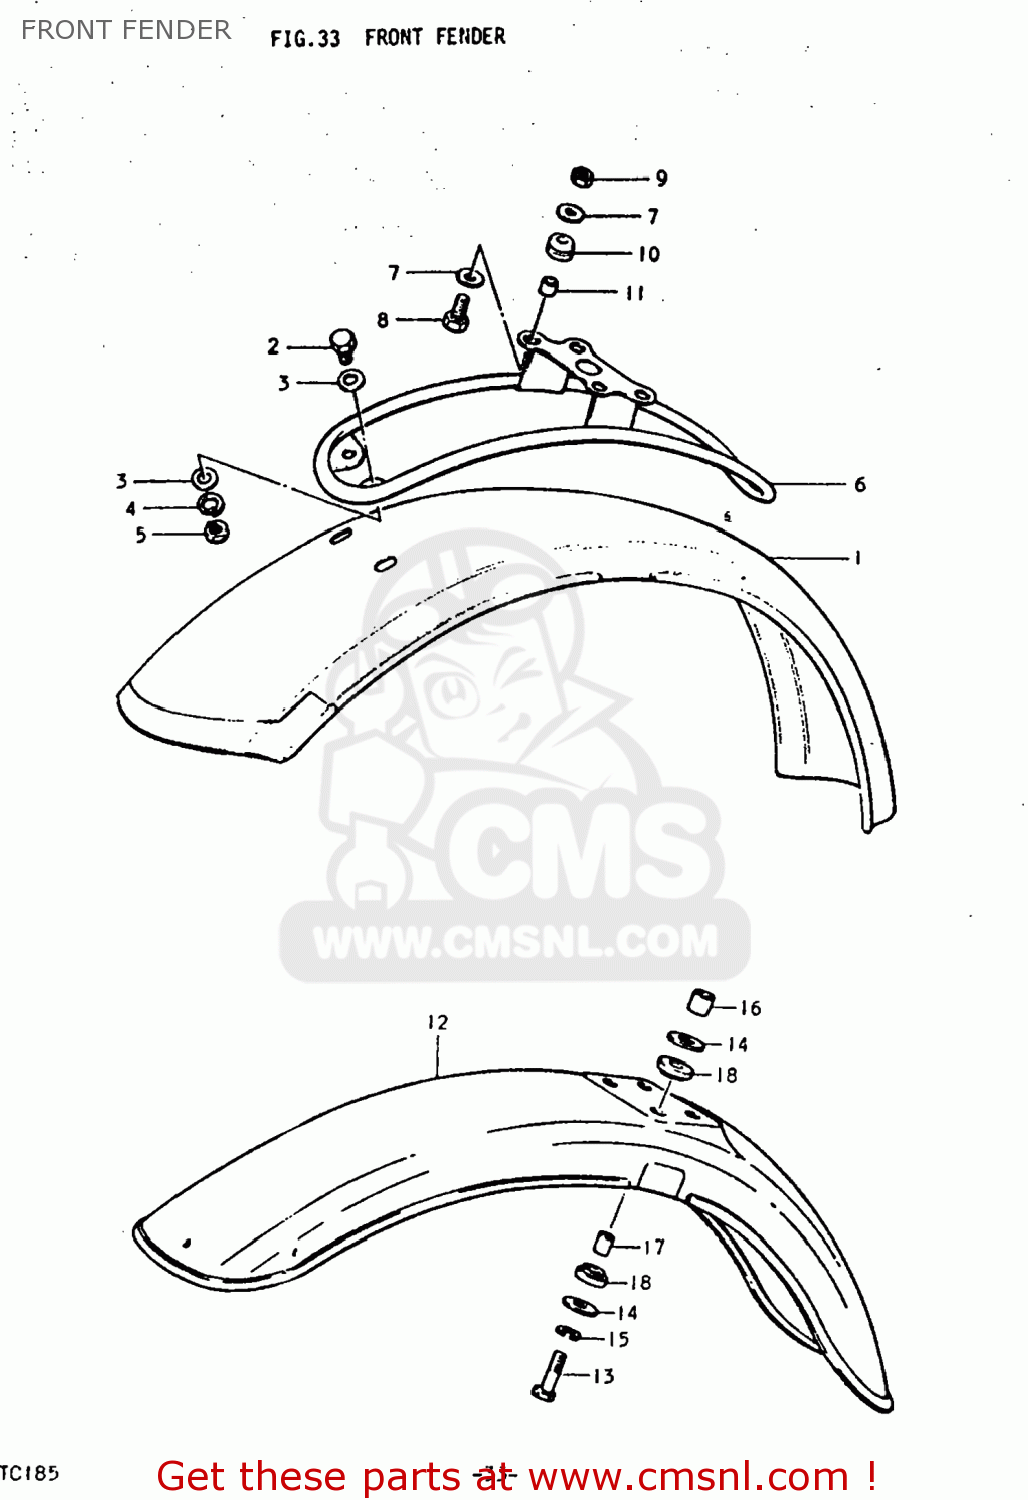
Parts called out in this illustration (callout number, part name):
1	FENDER,FRONT
2	BOLT
3	WASHER
4	LOCK WASHER
5	NUT
6	BRACE,FRONT FENDER
7	WASHER (6.5X20X1.2)
8	BOLT
9	NUT
10	CUSHION
11	SPACER(6.1X9X7.5)
12	FENDER,FRONT
13	BOLT
14	WASHER (6.5X24X1.2)
15	LOCK WASHER
16	SPACER (6.8X10X20)
17	SPACER (6.5X10.5X13.5)
18	CUSHION
